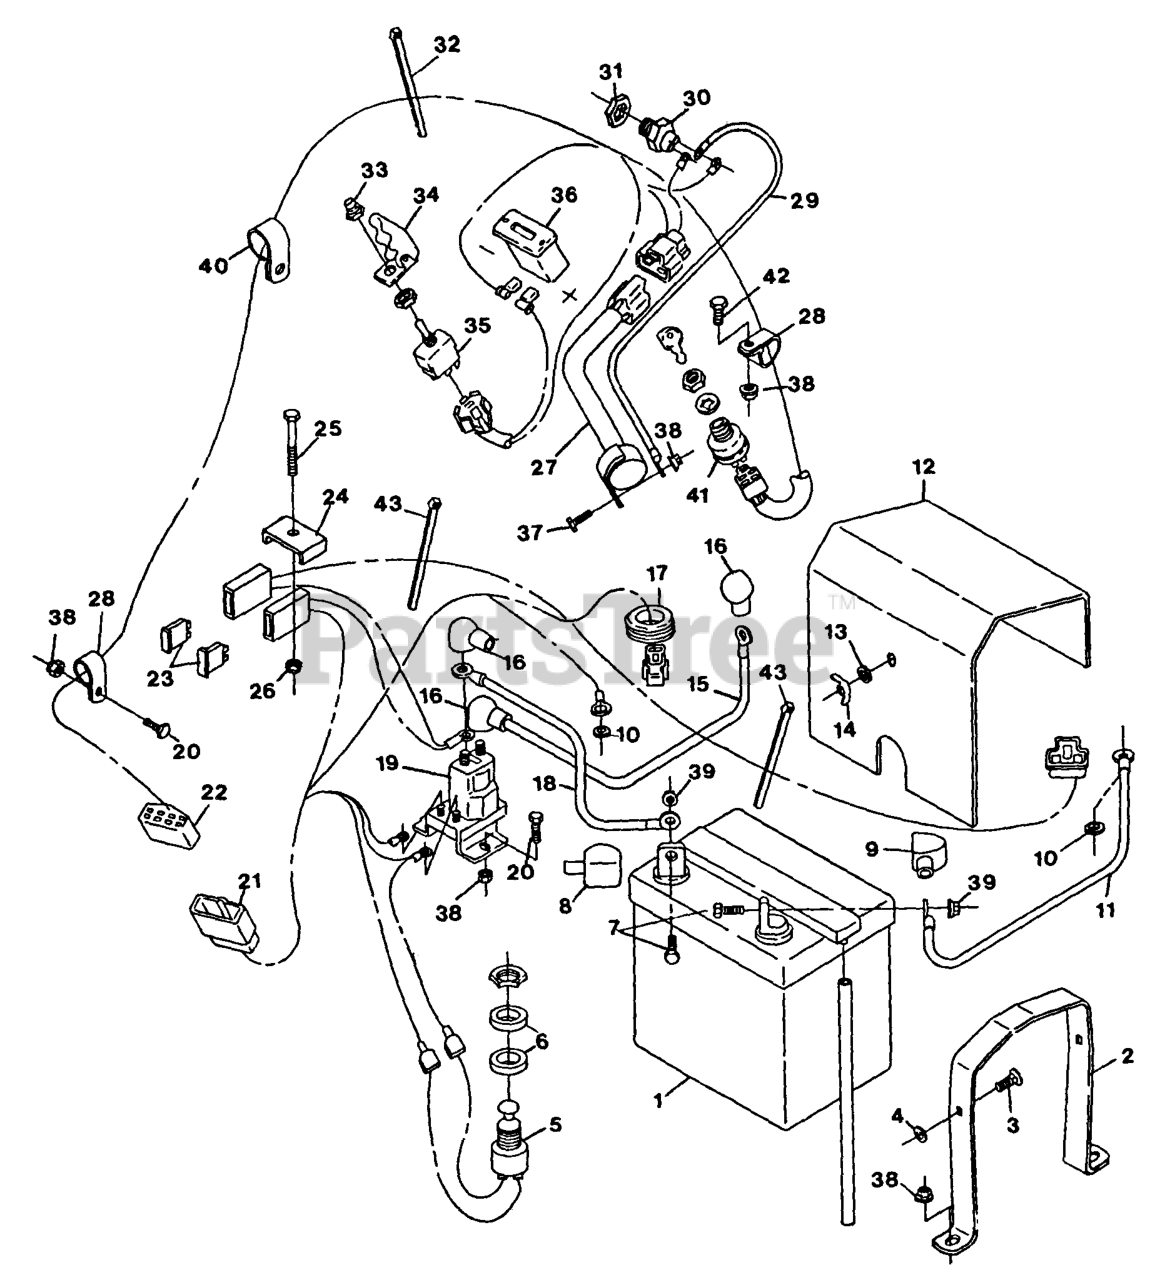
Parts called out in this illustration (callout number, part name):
1	Battery, 12v Manifold
2	STRAP,BATTERY HOLDDOWN
3	BOLT-CARR
4	NUT-RETAINING
5	SWITCH,PUSH BUTTON
9	INSULATOR, BATTERY -
14	NUT-WING
16	INSULATOR-SOLENOID
17	GROMMET
21	HARNESS,HYDRO ENGDECK
23	FUSE-BLADE TYPE, 20 AMP
24	CLIP-FUSE BLOCK PLTD
28	CLIP-LOOM
30	SWITCH,OPERATOR CNTRL
32	TIE-PLASTIC
33	BOOT-SWITCH, TOGGLE
36	METER-HOUR
40	CLIP-LOOM
